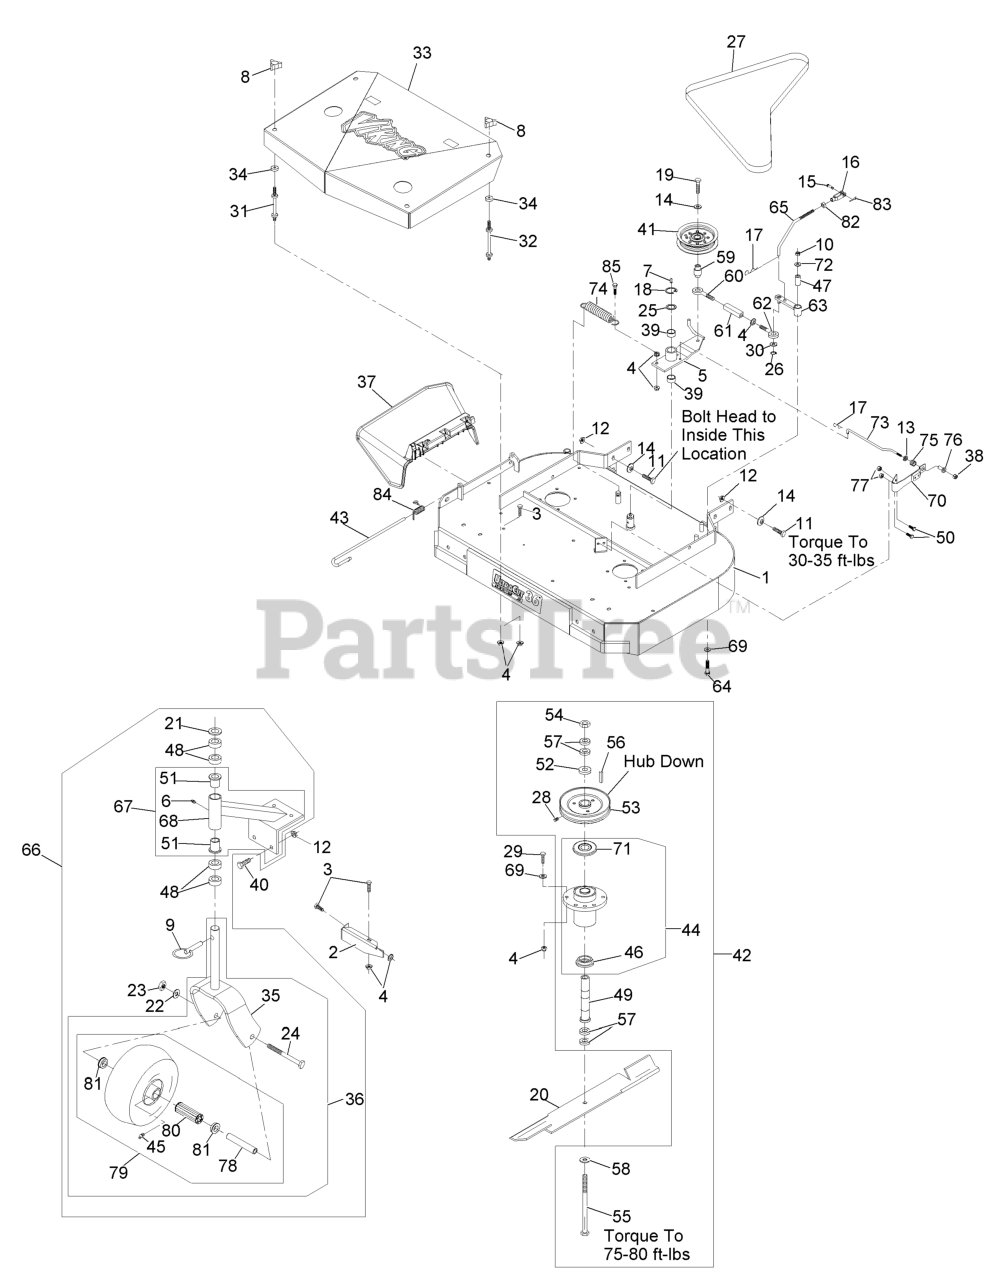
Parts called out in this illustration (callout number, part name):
1	ASM,DECK 36 RIGID
2	BAFFLE-DOGLEG
3	SCREW-HH
5	IDLER ARM ASM
6	FITTING-GREASE
7	FITTING-GREASE
8	KNOB-3 PRONG
10	NUT-LOCK, NI
11	SCREW-HH
12	NUT-HHF, WHIZ
13	RING-PUSH ON
14	WASHER-BELLEVILLE
15	PIN-CLEVIS
16	YOKE-ADJUSTABLE
17	PIN-COTTER
18	RING-RETAINING, EXT
19	SCREW-HH
21	WASHER-FLAT
22	WASHER-LOCK
23	NUT-HH
24	SCREW-HH
25	WASHER-SPINDLE
26	RING-RETAINING, EXT
27	BELT,BLADE VIKING HYD 36
28	SETSCREW
29	SCREW-HH
30	WASHER-PLAIN
31	STUD-SHIELD, BELT (SHORT)
32	STUD-SHIELD, BELT (LONG)
33	ASM,SHIELD W/DECALS 36 VI
35	FORK-CASTER
36	ASM,CASTER/WHEEL
37	CHUTE DEFLECTOR XRK M056
38	NUT-LOCK, NI
39	SLEEVE-BEARING
40	SCREW-HH
42	ASM, CUTTER HOUSING OUTER
43	PIN-CHUTE
44	KIT, CUTTER HOUSING
45	FITTING-GREASE
46	SPACER-GUARD, BOTTOM
47	TUBE-PIVOT
48	SPACER-CASTER
49	TUBE-SPINDLE, SHORT
50	SCREW-HH
51	BEARING-FLANGED
52	WASHER-RETAINER, SHEAVE
53	SHEAVE
54	NUT-HEX
55	SCREW-CAP, HH
58	WASHER-SPRING
59	BUSHING-ENGAGEMENT
60	EYEBOLT-THREAD, LH
61	BODY-TURNBUCKLE
62	EYEBOLT-THREAD, RH
63	ARM-ASSIST, 32/36
64	SCREW-HH
65	ARM-LINKAGE, ASSIST
66	ASM-CASTER MNT W/WEIGHT
67	ASM,CSTR SUPPORT W/WEIGHT
69	WASHER-SPRING
70	PAD AND SPRING ASM
71	GUARD-BEARING, TOP
72	WASHER-FLAT
73	ROD-BRAKE
74	SPRING-EXTENSION
75	SPRING-COMPRESSION
76	SPACER-FLANGED
77	NUT-LOCK, NI
79	KIT, SP CASTER WHEEL REPL
80	BEARING
81	BUSHING
82	NUT-HEX
83	PIN-COTTER
84	SPRING, TORSION
85	SCREW-HH, SPECIAL
